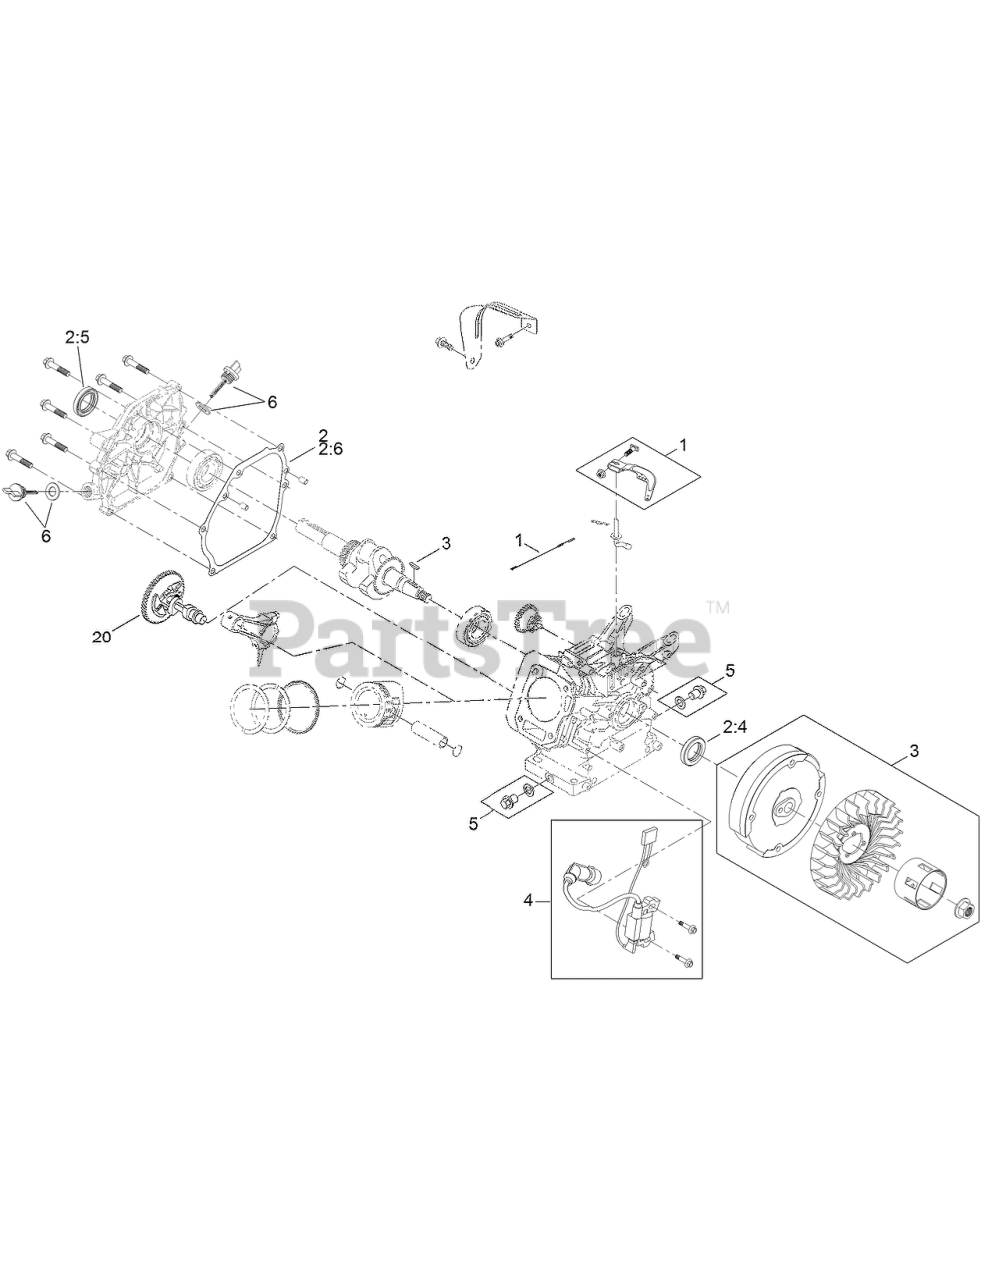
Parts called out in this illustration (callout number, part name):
1	GOVERNOR KIT
2	GASKET AND SEAL KIT
2:4	Seal-Oil
2:5	Seal-Oil
2:6	GASKET-COVER, CRANKCASE
3	RECOIL FLYWHEEL KIT
4	IGNITION KIT
5	DRAIN PLUG KIT
6	DIPSTICK AND O-RING KIT
20	CAMSHAFT
